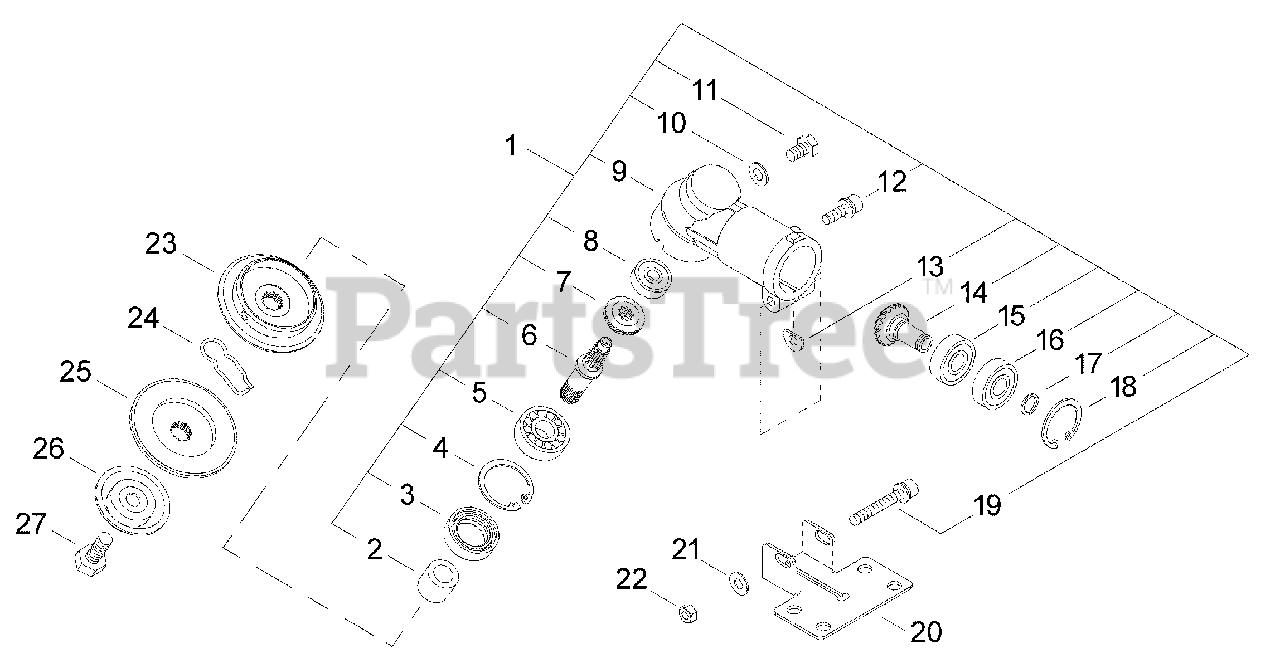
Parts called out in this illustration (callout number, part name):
1	GEAR CASE ASSY
2	SPACER
3	SEAL, OIL
4	RING, SNAP Ø32
5	BEARING, BALL 6201
6	SHAFT, GEAR
7	GEAR, BEVEL
8	BEARING, BALL
9	CASE, GEAR
10	WASHER
11	BOLT M6×10
12	BOLT M5×16
13	D-WASHER
14	GEAR, PINION
15	BEARING, BALL 6901
16	BEARING, BALL 6901ZZ
17	RING, SNAP Ø12
18	RING, SNAP Ø24
19	BOLT M6×40
20	PLATE, SHIELD MOUNTING
21	WASHER 6.5×13×1
22	NUT, HEX M6
23	PLATE, ADAPTOR - UPPER
24	CLIP, BLADE
25	PLATE, ADAPTOR - LOWER
26	GUARD, BOLT
27	BOLT 8
